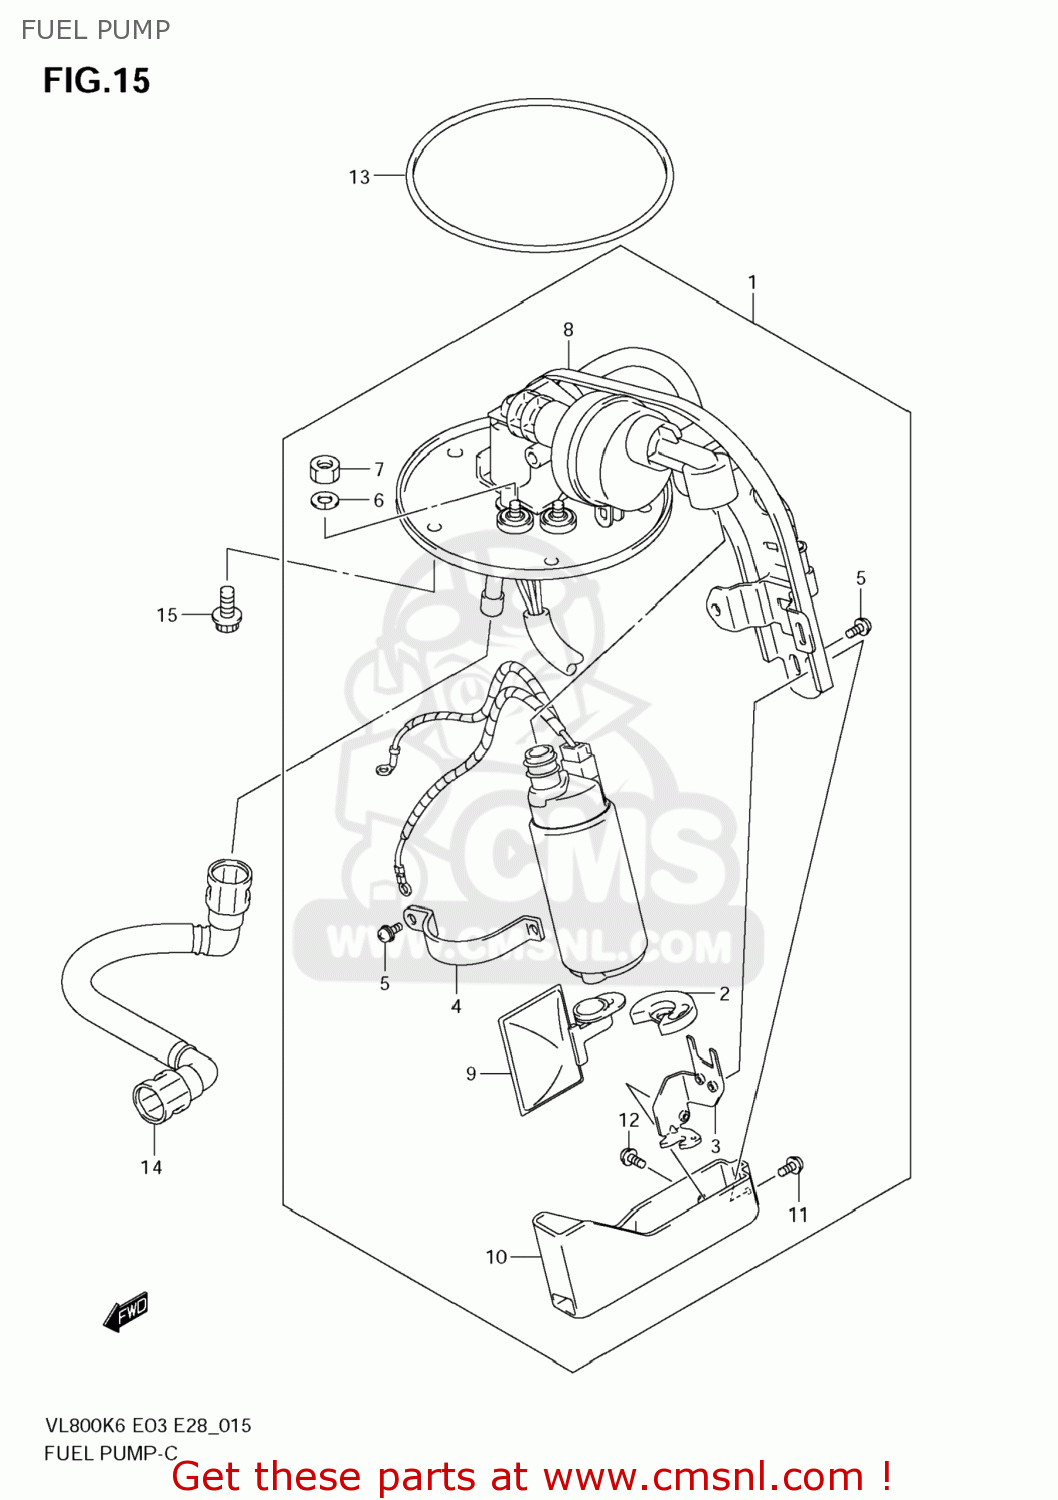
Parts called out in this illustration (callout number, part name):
1	PUMP ASSY,FUEL
2	CUSHION
3	HOLDER
4	BAND,FUEL PUMP
5	SCREW
6	WASHER,SPRING
7	NUT
8	PLATE ASSY
9	STRAINER
10	VESSEL
11	SCREW
12	SCREW
13	O RING,FUEL PUMP
14	HOSE,FUEL
15	BOLT
